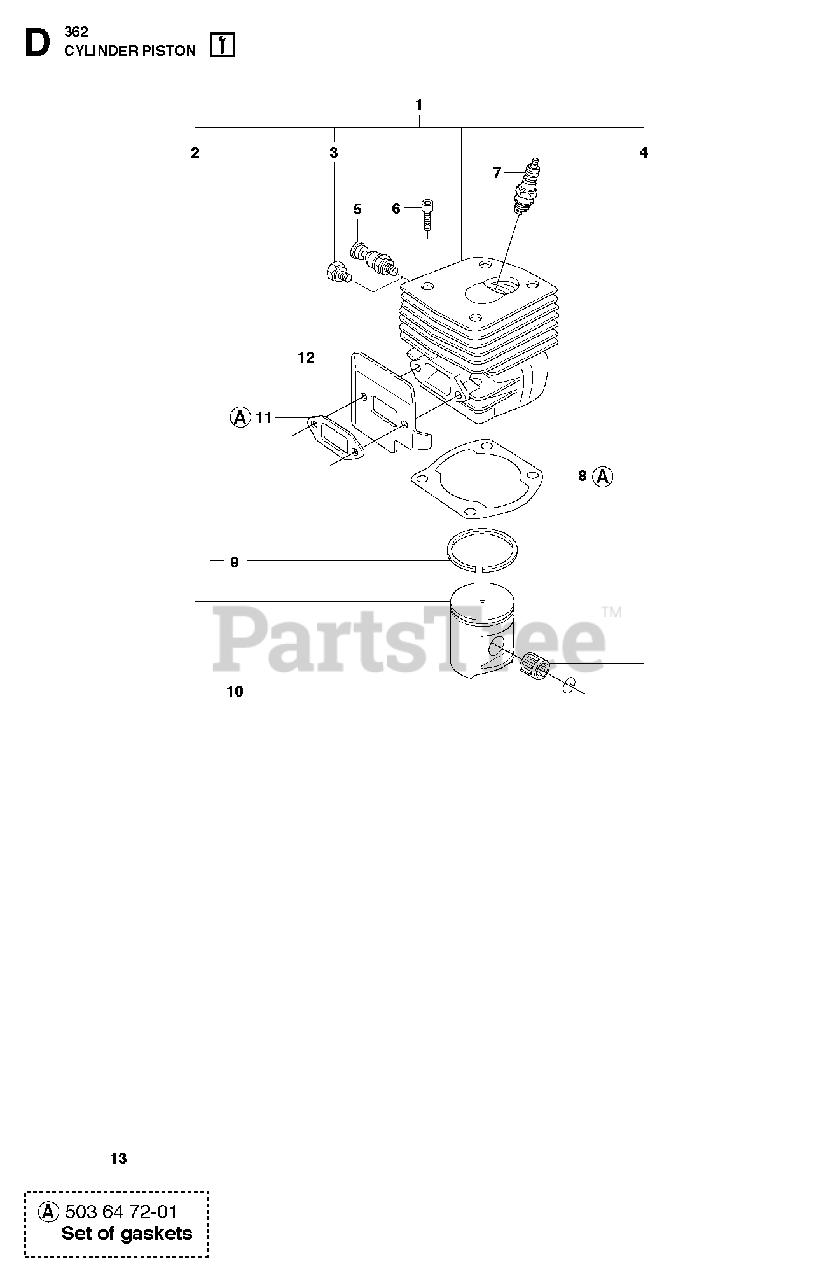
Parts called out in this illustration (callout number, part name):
1	CYLINDER
2	PISTON CPL 48 MM
3	CYLINDER PLUG
4	SUPPORT BUSHING
5	DECOMPRESSION VALVE
6	SCREW MC6S 5X25
7	SPARK PLUG RCJ7Y
8	GASKET
9	PISTON RING
10	WRIST PIN CLIP
11	GASKET
13	GASKET SET
